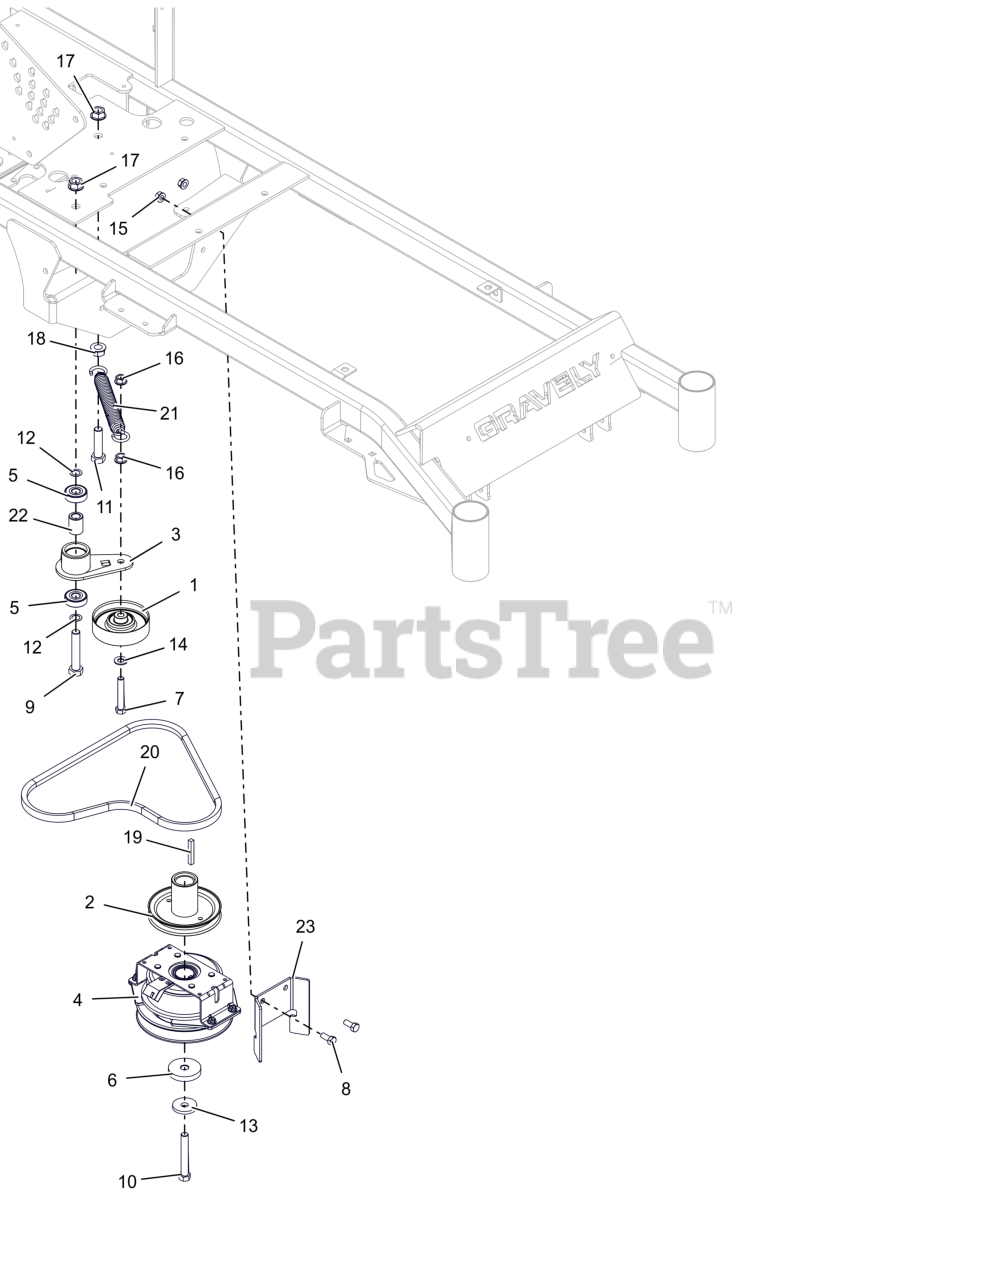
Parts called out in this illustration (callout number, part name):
1	IDLER, FLAT 3.5" NO FLANGES
2	SHEAVE, ENGINE 4.50 X 1.127
3	WMT- IDLER ARM
4	CLUTCH, OGURA GT1.5-AR11(D)
5	BRG-BALL .500X1.38X.437
6	SPACER, .474/.459X2.00X.350
7	BLT,HEX .38-16X2.25 G5 ZCC
8	BLT,HEX .31-18X.75 G5 ZCC
9	BLT,HEX .50-13X2.75 G5 ZCC
10	BLT, HEX 0.4375-20X3 G8 ZCC NT
11	BLT, HEX .50-13X2.00 G5 ZCC
12	WASHER, .500X.750X.020 THRUST
13	WASHER, 7/16" SPRING DISK
14	WSHR,FLT .406X.812X.065 ZCC
15	NUT,LK-CTR-FLG .31-18 GF ZCC
16	NUT-LK-CTR-FLG .375-16 GF ZCC
17	NUT-LK-CTR-FLG .500-13 GG ZCC
18	NUT, SPNLK-FLG .50-13 G5 ZCC
19	KEY-STR .25X1.75X.25
20	BELT- A SECTION
21	SPRING- EXTENSION
22	SPACER .510 X .867 X 1.1485
23	BRKT- CLUTCH STOP (RED)
